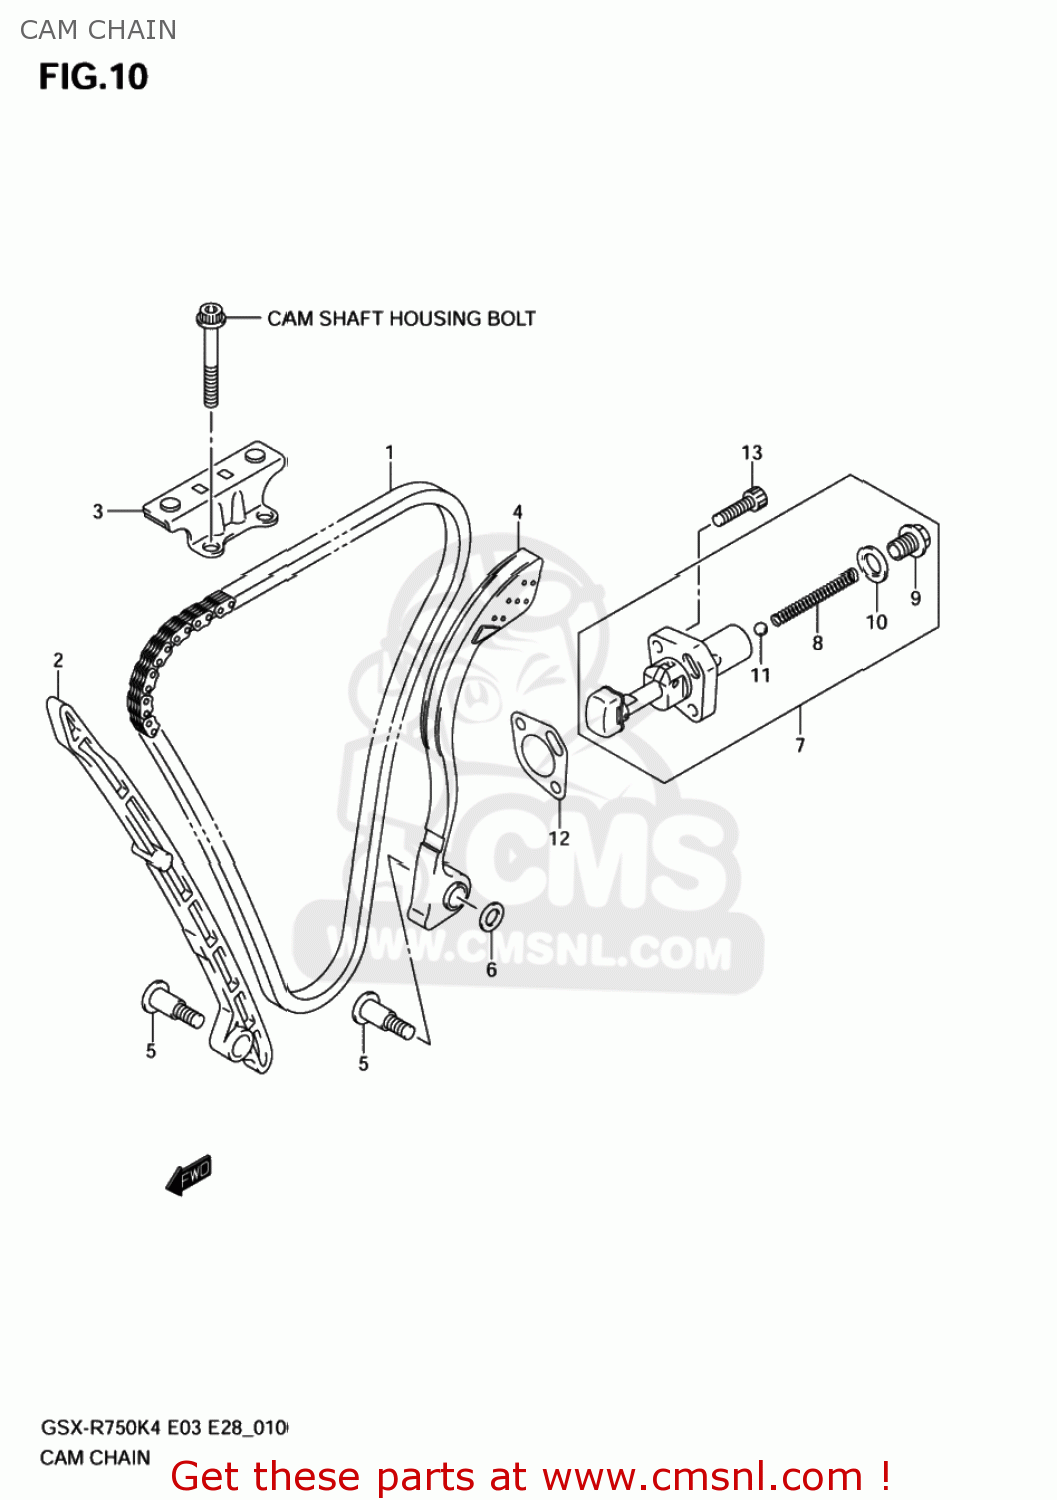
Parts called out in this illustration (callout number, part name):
1	CHAIN COMP,CAMSHAFT DRIVE
2	GUIDE,CAM CHAIN NO.1
3	GUIDE CAM CHAIN NO,2
4	TENSIONER,CAM CHAIN
5	BOLT,CAM CHAIN TENSIONER/GUIDE
6	WASHER,CAM CHAIN TNSN
7	ADJUSTER ASSY,
8	SPRING
9	PLUG,FR TENSIONER ADJ
10	GASKET,TENSIONER ADJUSTER (NAS)
11	BALL
12	GASKET,TENSIONER ADJUSTER (NAS)
13	BOLT,CL.COVER
